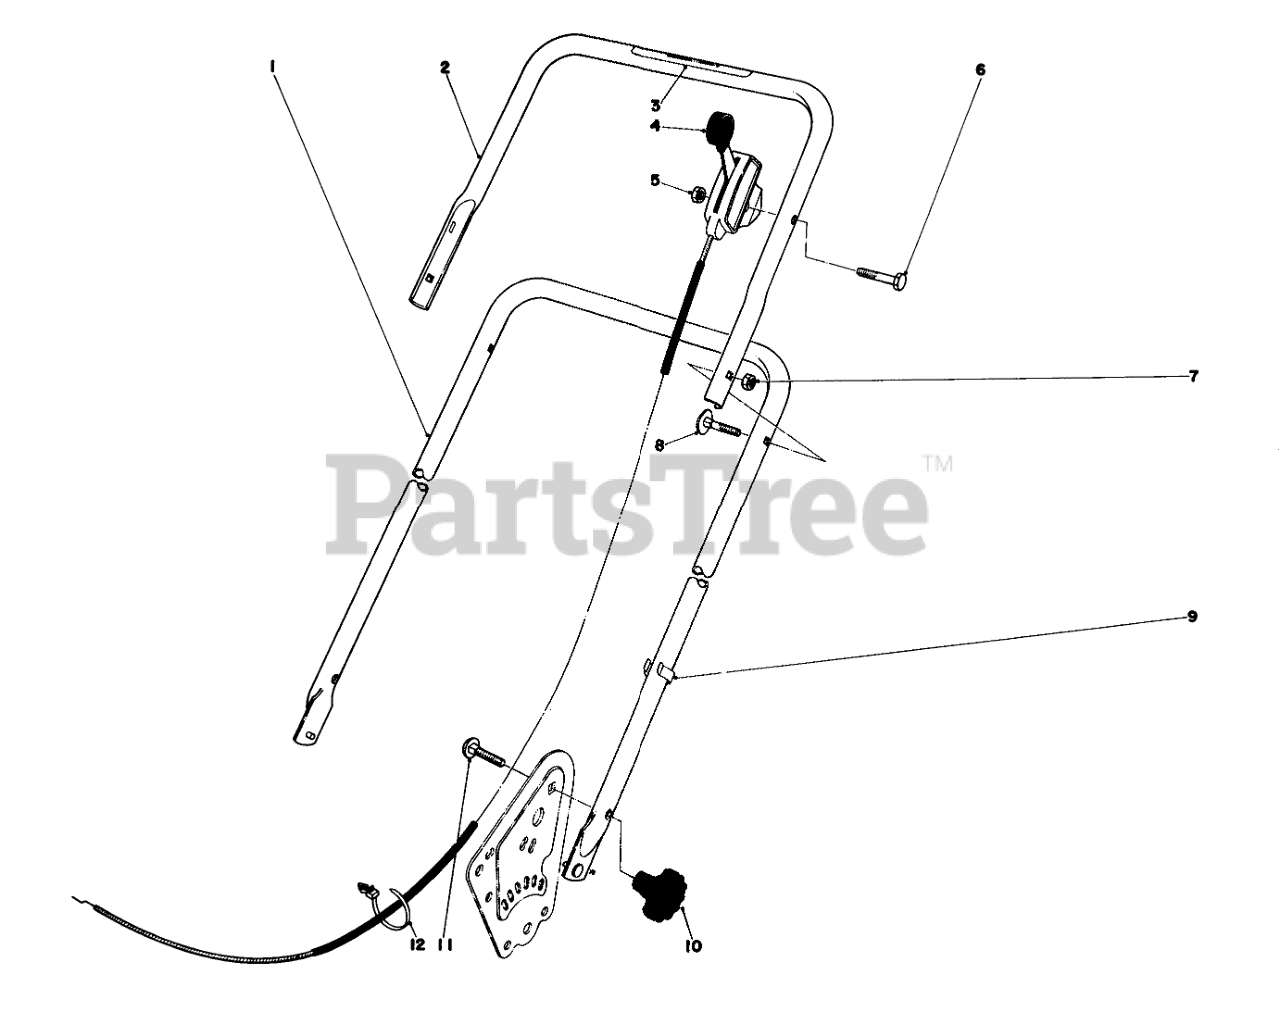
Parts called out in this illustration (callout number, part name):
1	Lower Handle
2	Upper Handle
3	Danger-Decal
4	Throttle Control
5	NUT-LOCK
6	SCREW-HH
7	Nut
8	HANDLE SCREW
11	Bolt-Carriage
12	TIE-MOUNT, PUSH
